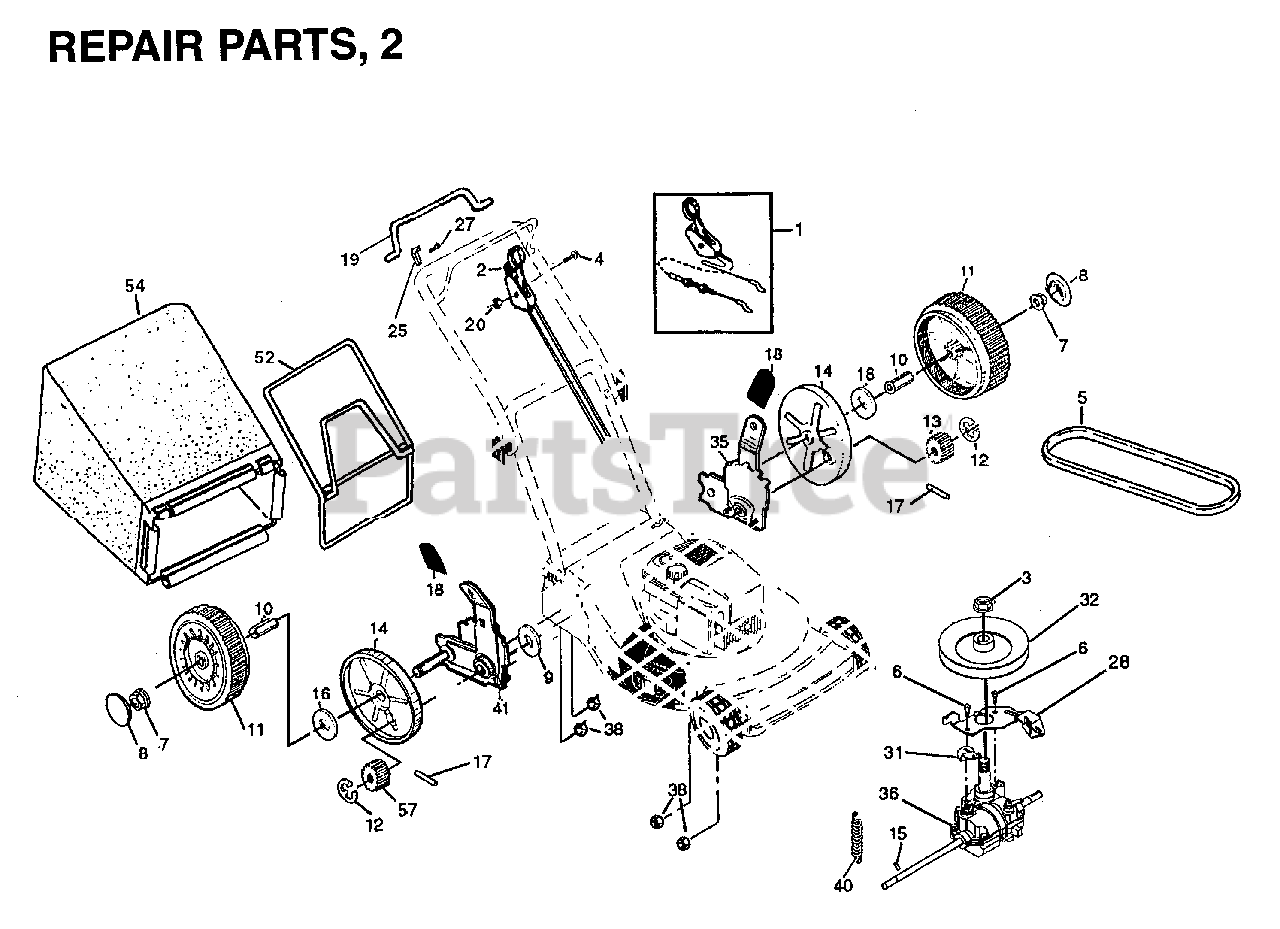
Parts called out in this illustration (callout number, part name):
2	KIT/HEAD CONTROL
3	METRIC NUT
4	SCREW 1/4-20 X 2.12
7	HEX FLANGE LOCKNT
9	THRUST WASHER
11	WHEEL & TIRE 8 X 2
12	E-RING 7/16 RE
14	DUST SHROUD PM
15	PIN.SPRING.THRUST
16	WASHER FLUT
17	DRIVE PAWL
18	SELECTOR KNOB
20	NUT.CROWNLOCK.1/4
25	BRACKET UPSTOP
38	NUT.CROWNLOCK.1/4
